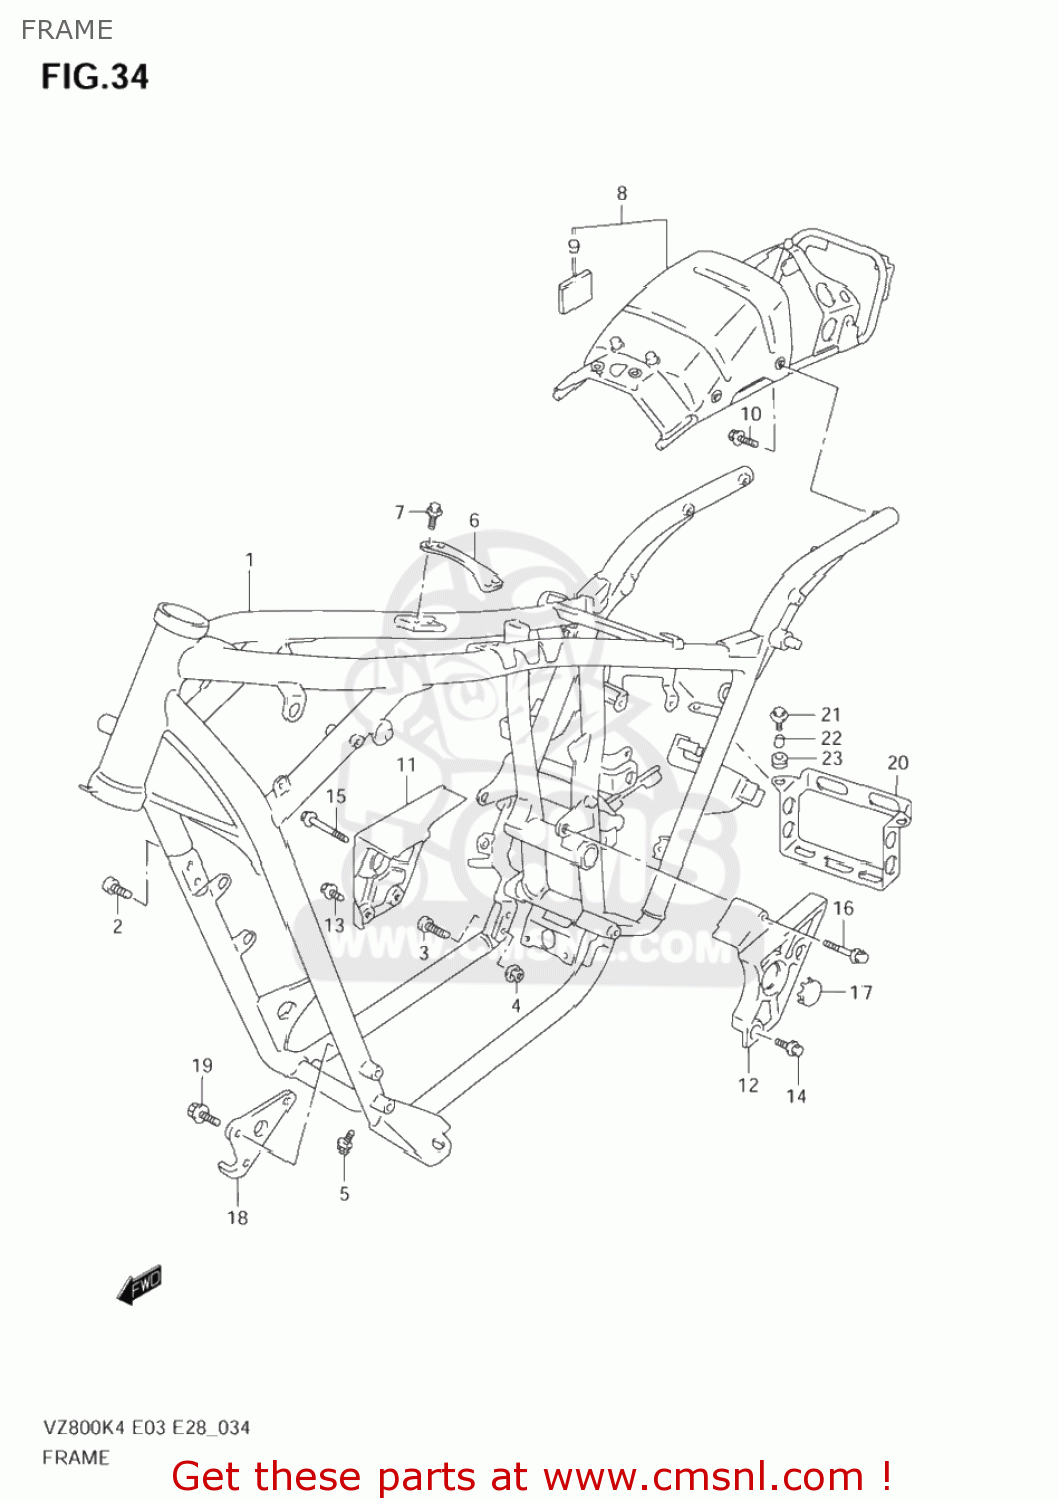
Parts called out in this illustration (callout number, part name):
1	FRAME(BLACK)
2	BOLT
3	BOLT
4	NUT
5	BOLT
6	PLATE,FRAME BODY
7	BOLT(8X16)
8	BRACE ASSY,RR FRAME
9	PAD
10	BOLT, FRONT
11	COVER,PIVOT,R
12	COVER,PIVOT,L
13	BOLT(8X16)
14	BOLT,PIVOT COVER
15	BOLT(8X16)
16	BOLT,PIVOT COVER UPR,L
17	CAP,RR SWINGING ARM PIVOT,R
18	PLATE,ENGINE MOUNT NO.1,L
19	BOLT
20	HOLDER,BATTERY
21	BOLT(6X16)
22	SPACER(6.5X9X8)
23	CUSHION
